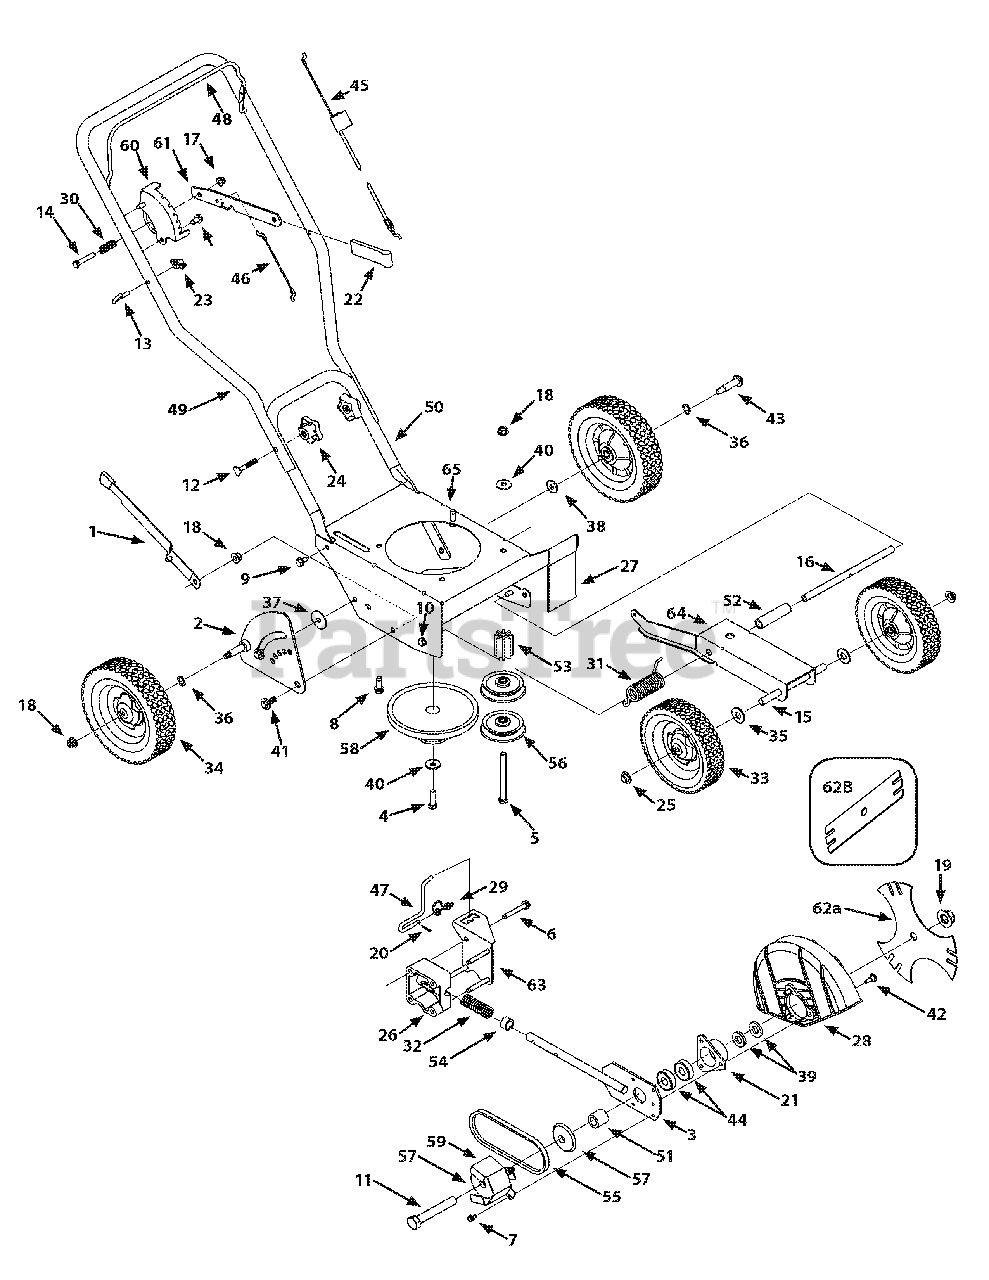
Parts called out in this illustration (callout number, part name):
1	Curb Height Adjustment Lever
2	Curb Height Adjuster Plate
3	Blade Plate Assembly
4	Screw 3/8 -24
5	Screw 3/8-16
6	Hex Screw, 5/16-18
7	Self-tapping Screw, 1/4-20
8	Screw, 3/8-16
9	Hex Screw, 5/16-12
10	Hex Screw 5/16-18
11	Hex Screw, 5/8-18
12	Carriage Bolt, 5/16-18
13	Rope Guide (Eye Bolt)
14	Hex Screw, 5/16-18
15	Axle Shaft .50x6.65
16	Frame Spacer .50x9.25
17	Lock Flange Nut, 5/16-18
18	Flange Nut 3/8-16
19	Flange Nut, 5/8 -18
20	Clevis Pin 3/32 x .625
21	Bearing Cup
24	Star Knob
25	Push Cap 1/2" rod
26	Bearing Block
27	Debris Guard
28	Blade Guard
29	Double Torsion Spring
30	Compression Spring
31	Torsion Spring
32	Compression Spring
33	Wheel 7 x 1.75 T-Tread
34	Wheel 8 x 1.75 T-Tread
35	Flat Washer 1/2 x 1.25 x .10
36	Wave Washer .531 x .781 x .013
37	Flat Washer, .385 x 1.5 x .075
38	Flat Washer .385 x 1.0 x .135
39	Flat Washer .635x1.24x.181
40	Bell Washer,.396 x 1.140
41	Shoulder Screw,3/8 -16
42	Shoulder Screw
43	Shoulder Screw, 3/8 -16
44	Bearing, .625 ID x 1.57 OD
45	Control Cable (Briggs & Stratton)
46	Wheel Adjustment Cable
47	Blade Adjustment Rod
48	Bail Handle
49	Upper Handle
50	Lower Handle
51	Spacer, .63 x 1.12 x 1.06
53	Pulley Mount Spacer
54	Spacer, .64 x.88 x .50
56	Flat Idler Pulley, 2.5 OD
58	Combination Flywheel Pulley
62A	Tri-Star Blade
64	Dual Wheel Bracket
